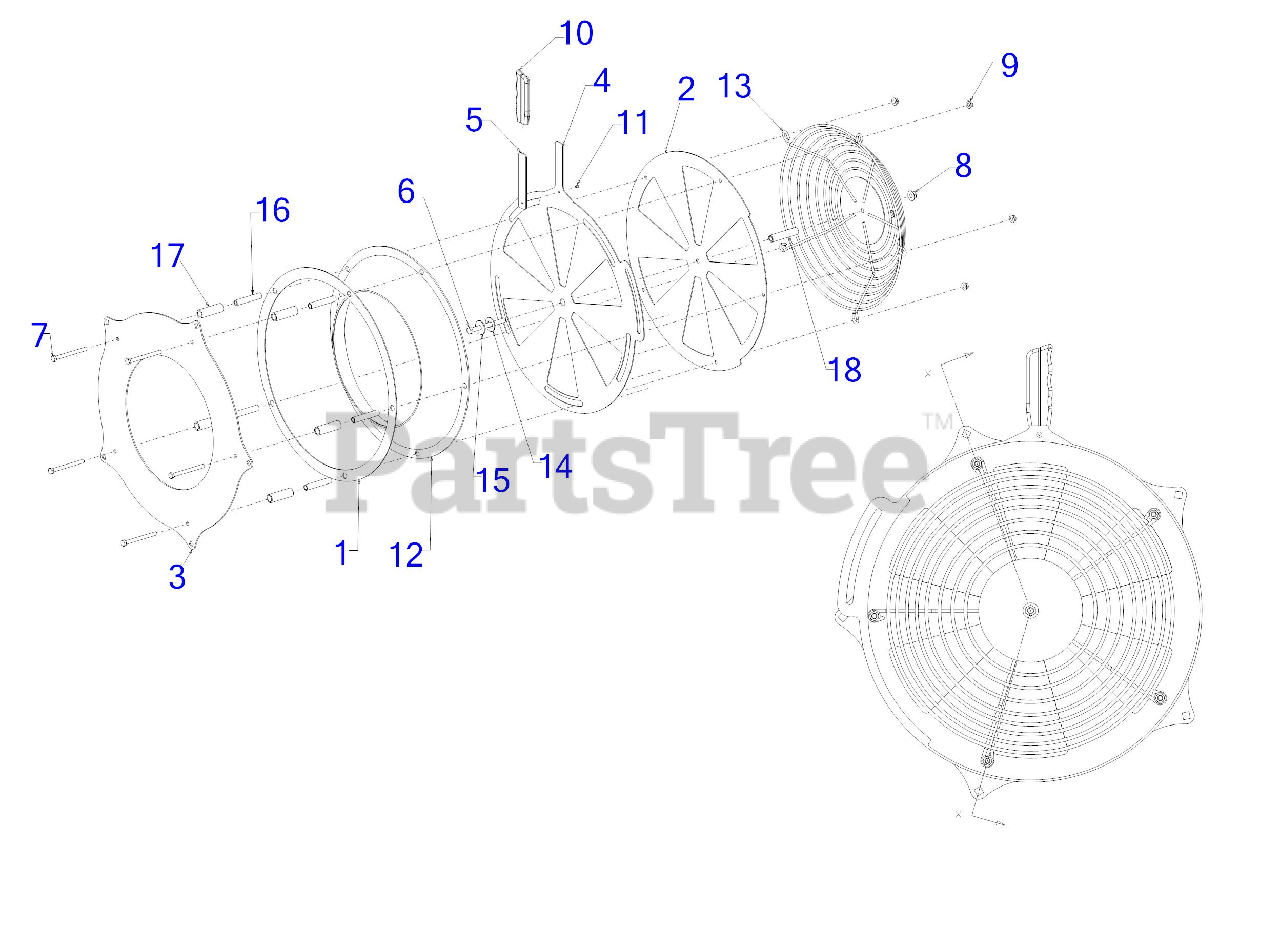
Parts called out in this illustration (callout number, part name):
6	SCREW 3/8-16 x 3.75 GR5
7	SCREW 5/16-18X3.5 GR5
8	FLANGE LOCK NUT
9	FLANGE NUT
12	BLOWER INLET BELL
14	FLAT WASHER NYLON 5/8
15	SHOULDER SPACER
16	SPACER .5 X .334 X 2.75
17	TUBE SPACER .75 X .525 X 2.375
18	SPACER .625 X 4.06 X 2.87
